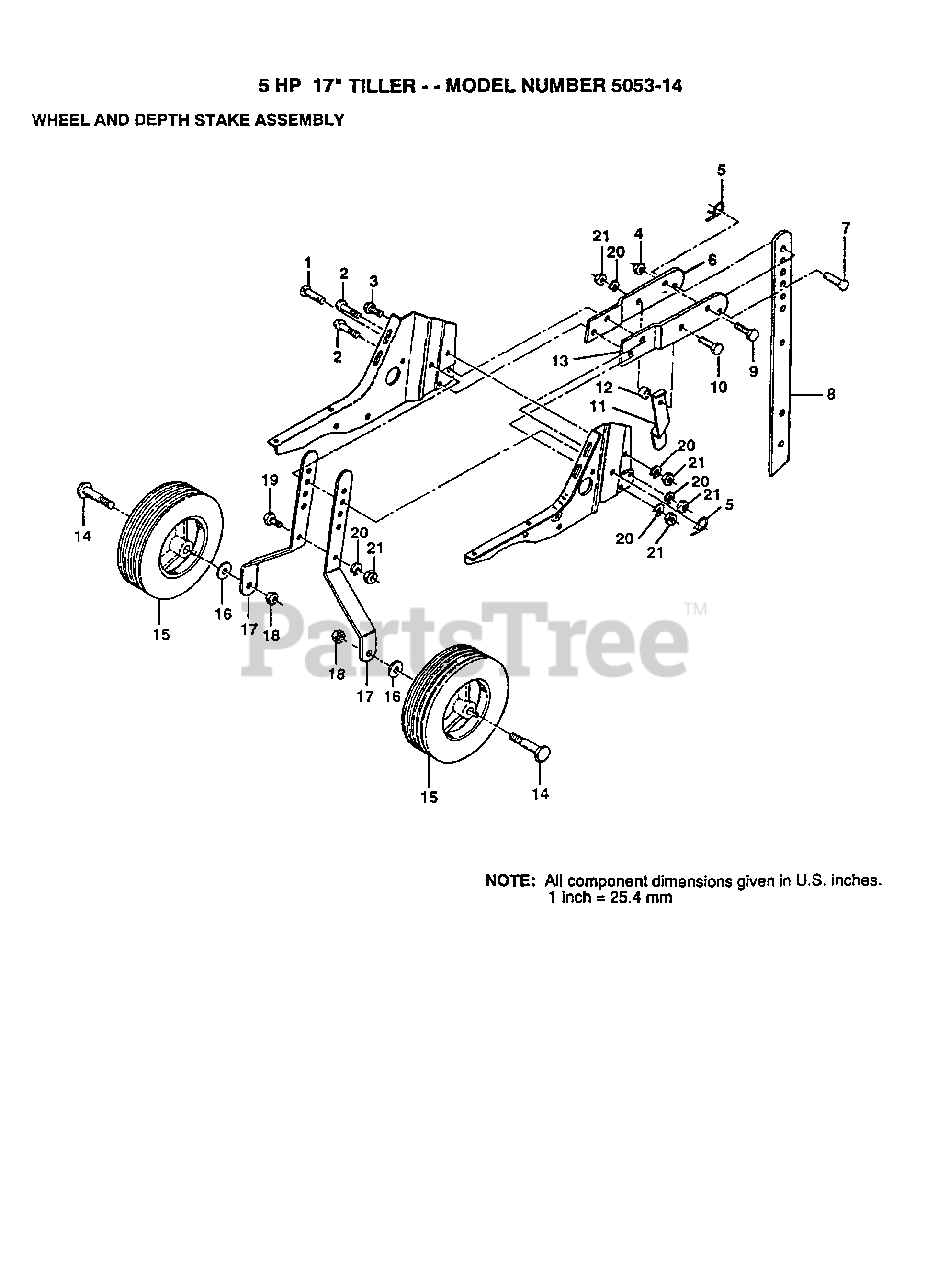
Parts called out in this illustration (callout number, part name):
1	DRILLED RIVET RT
3	BOLT
4	GRIPCO NUT
5	SPRING.RETAINER
9	BOLT.3/8-24X1-1/2
10	BOLT.HEX.5/16-1.5
11	STAKE SPRING TI
12	WASHER
14	BOLT SHOULDER
15	WHEEL TI
16	WASHER
20	LOCKWASHER
21	NUT.HEX.5/16-18
